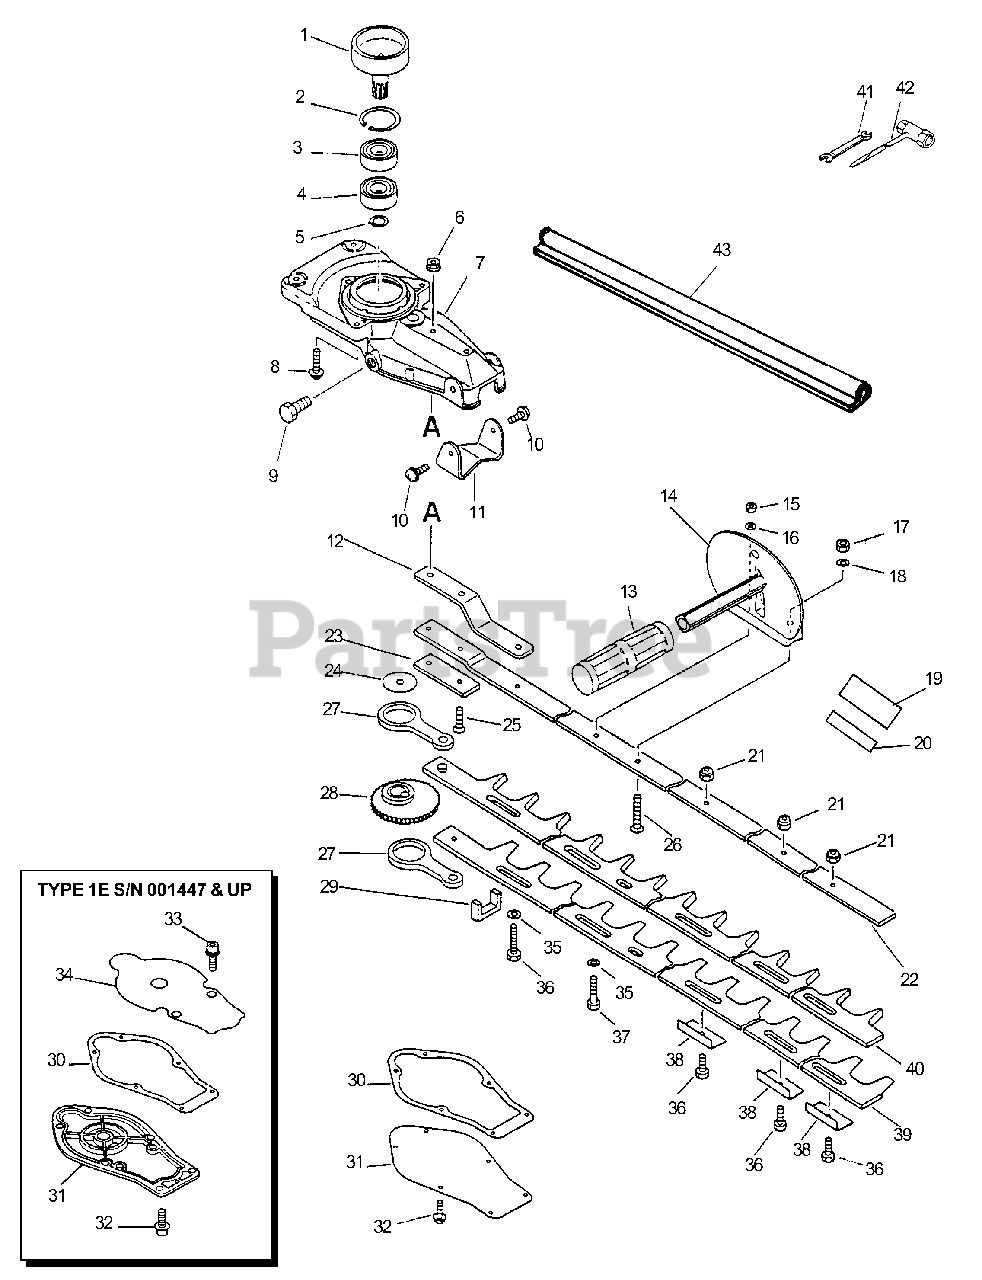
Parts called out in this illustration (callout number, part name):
1	DRUM, CLUTCH
2	E-RING 30
3	BEARING, BALL 6202
4	BEARING, BALL 6202
5	RING, SNAP 14
6	NUT, HEX M6
7	HOUSING, GEAR CASE
7	CASE, GEAR
8	SCREW 5×25
9	BOLT 8×8 SP
10	SCREW 5×10
11	STAND
12	PLATE, ANGLE
14	HANDLE, FRONT
15	NUT, LOCK 6
16	WASHER 5.5×18×1
17	NUT, LOCK M5
18	WASHER 5.5×18×1
19	LABEL, CAUTION
20	LABEL, CAUTION - ISO
21	NUT, LOCK 6
22	BAR, FRAME
23	PLATE, EYE
25	SCREW 6×25
26	SCREW 5×30
27	ROD, CONNECTING
30	GASKET, GEAR CASE
31	LID, GEAR CASE
31	COVER, GEAR CASE
32	BOLT 4×10
32	BOLT 4×12
33	BOLT 5×12
34	PLATE, GEAR CASE
35	WASHER 6.5×15.5×0.6
36	BOLT, CUTTER
38	INSULATOR
39	BLADE - LOWER
40	BLADE - UPPER
41	SPANNER 8×10
42	T-WRENCH 13×19×180
43	SCABBARD
